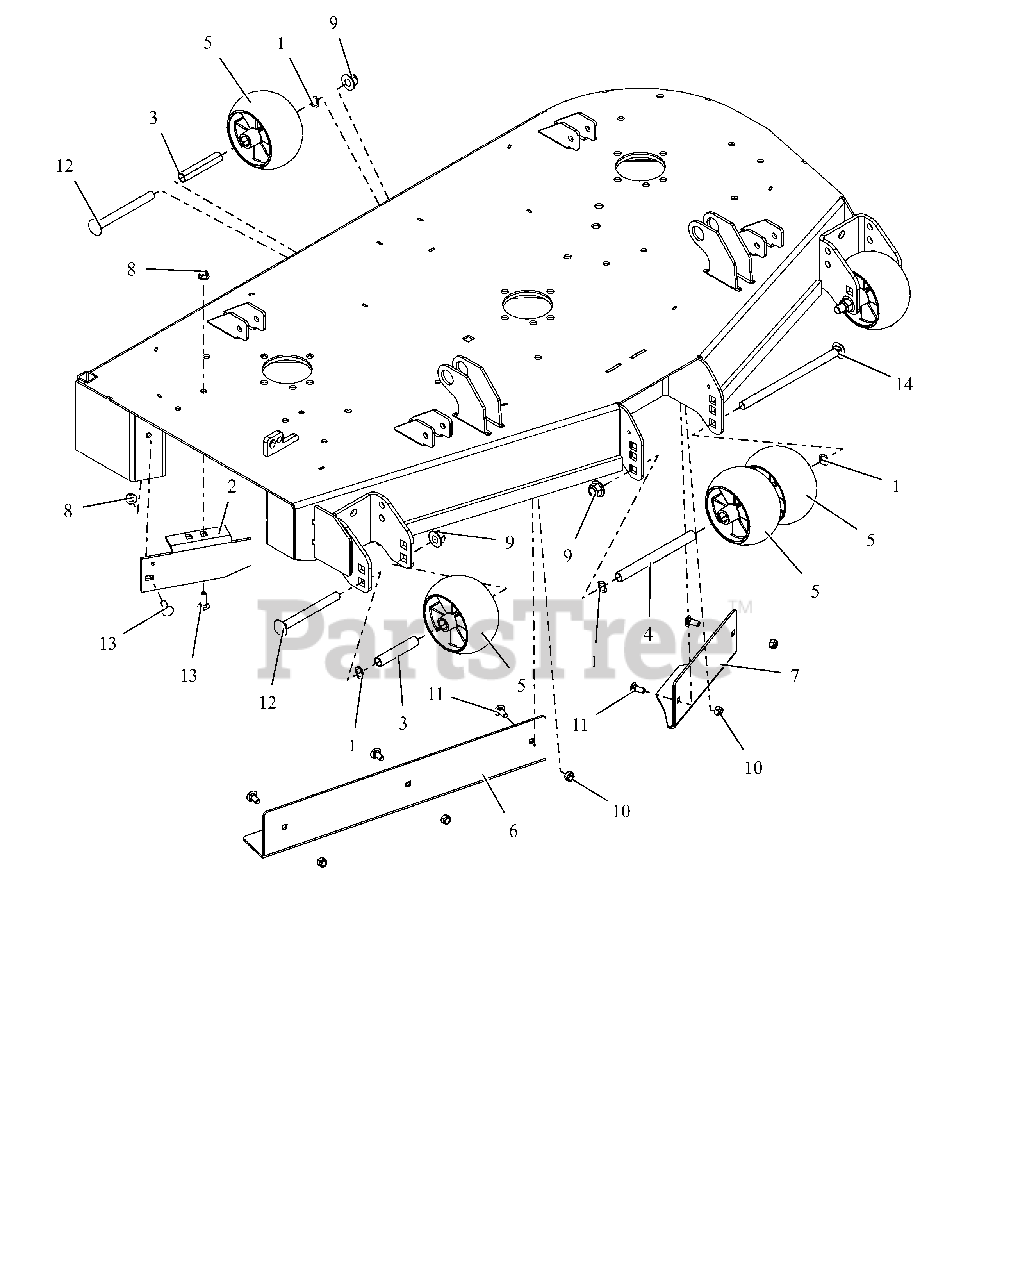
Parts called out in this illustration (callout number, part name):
1	WAVE WASHER .531X.781X.125FH
2	44"-48" SIDE DISCH BAFFLE -RED
3	SPACER, .510X.625X3.35
4	SPACER, .510X.625X6.50
5	ANTI-SCALP WHEEL - 5X3 CTR
6	BAFFLE, 48" RH VACUUM (RED)
7	BAFFLE, 44/48" LH VACUUM (RED)
8	NUT,NYL-FLG .31-18 GF ZCC
9	NUT,NYL-FLG .50-13 GF ZCC
10	NUT,NYL .31-18 G5 ZCC
11	BLT,RHSN .31-18X.75 G5 ZCC
12	BLT, RHSN .50-13X5.00 G5 ZCC
13	BLT,RHSN .31-18X1.00 G5 ZCC
14	BLT, RHSN .50-13X8.50 G5 ZCC
